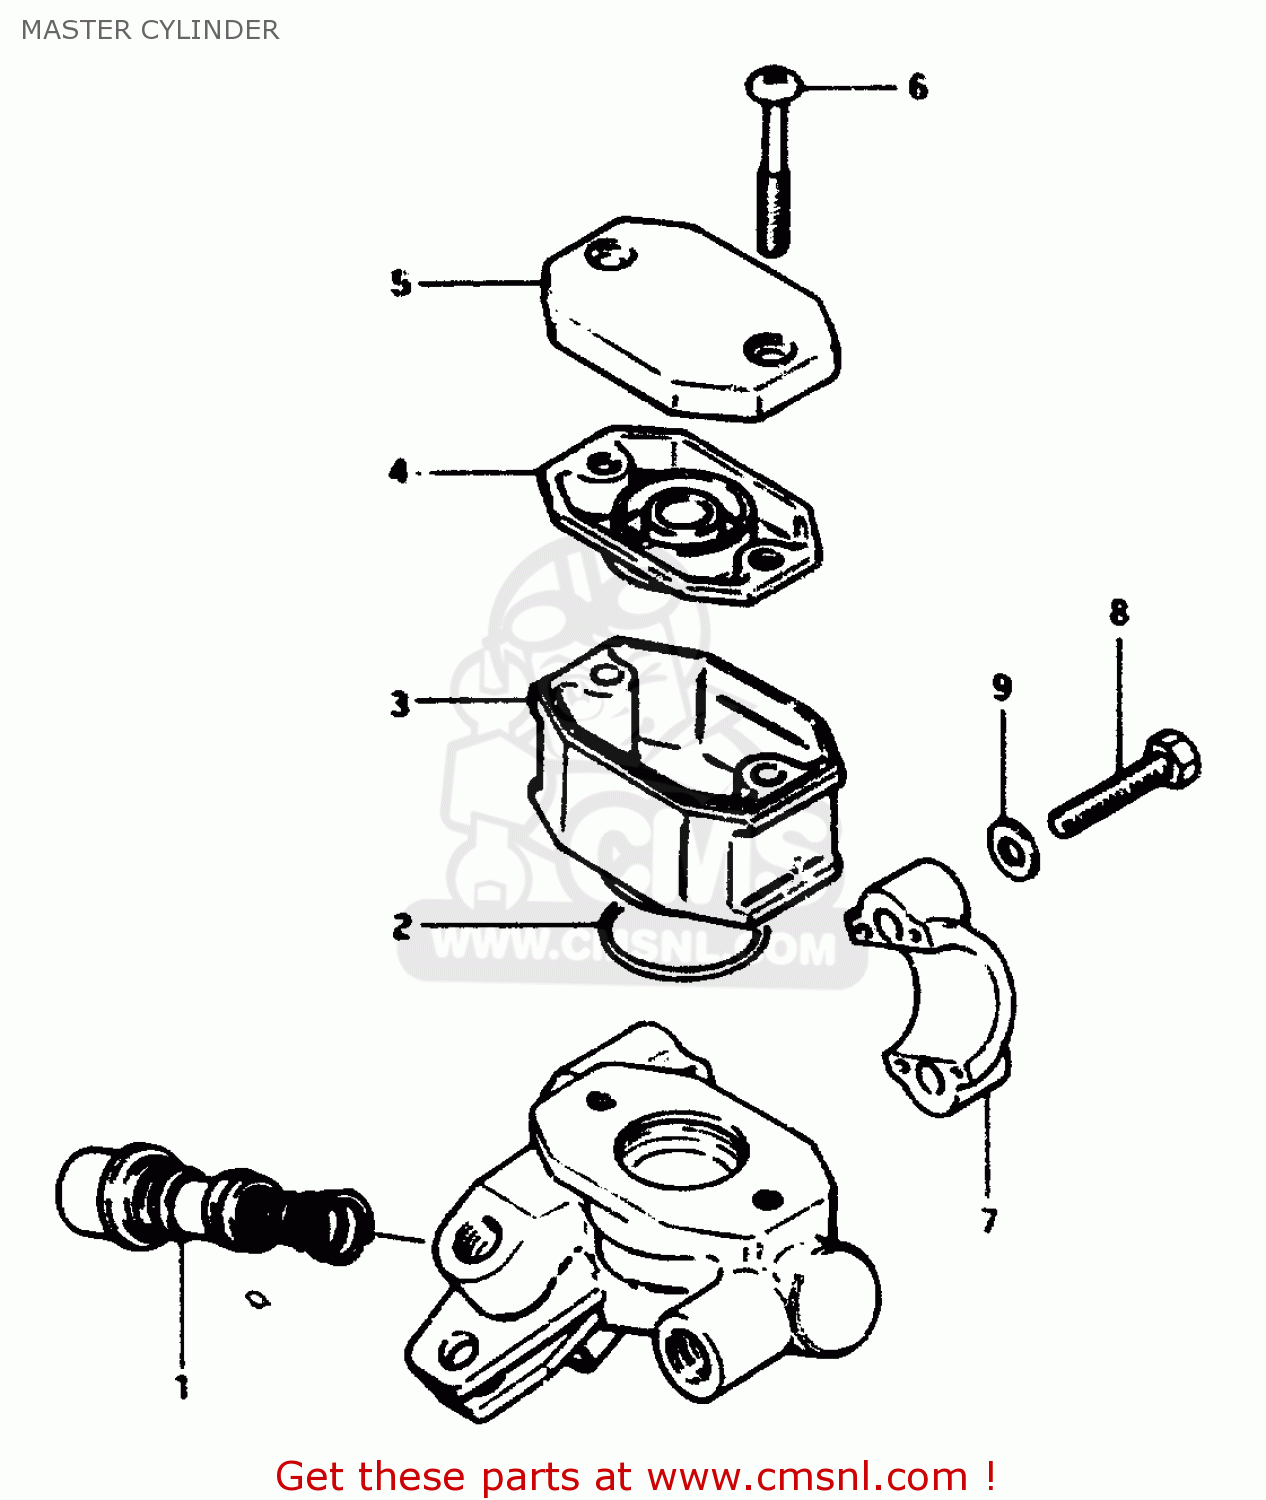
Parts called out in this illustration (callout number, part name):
1	PISTON & CUP SET
2	O RING
3	RESERVOIR
4	DIAPHRAGM
5	CAP,RESERVOIR
6	SCREW
7	HOLDER
8	BOLT
9	WASHER
